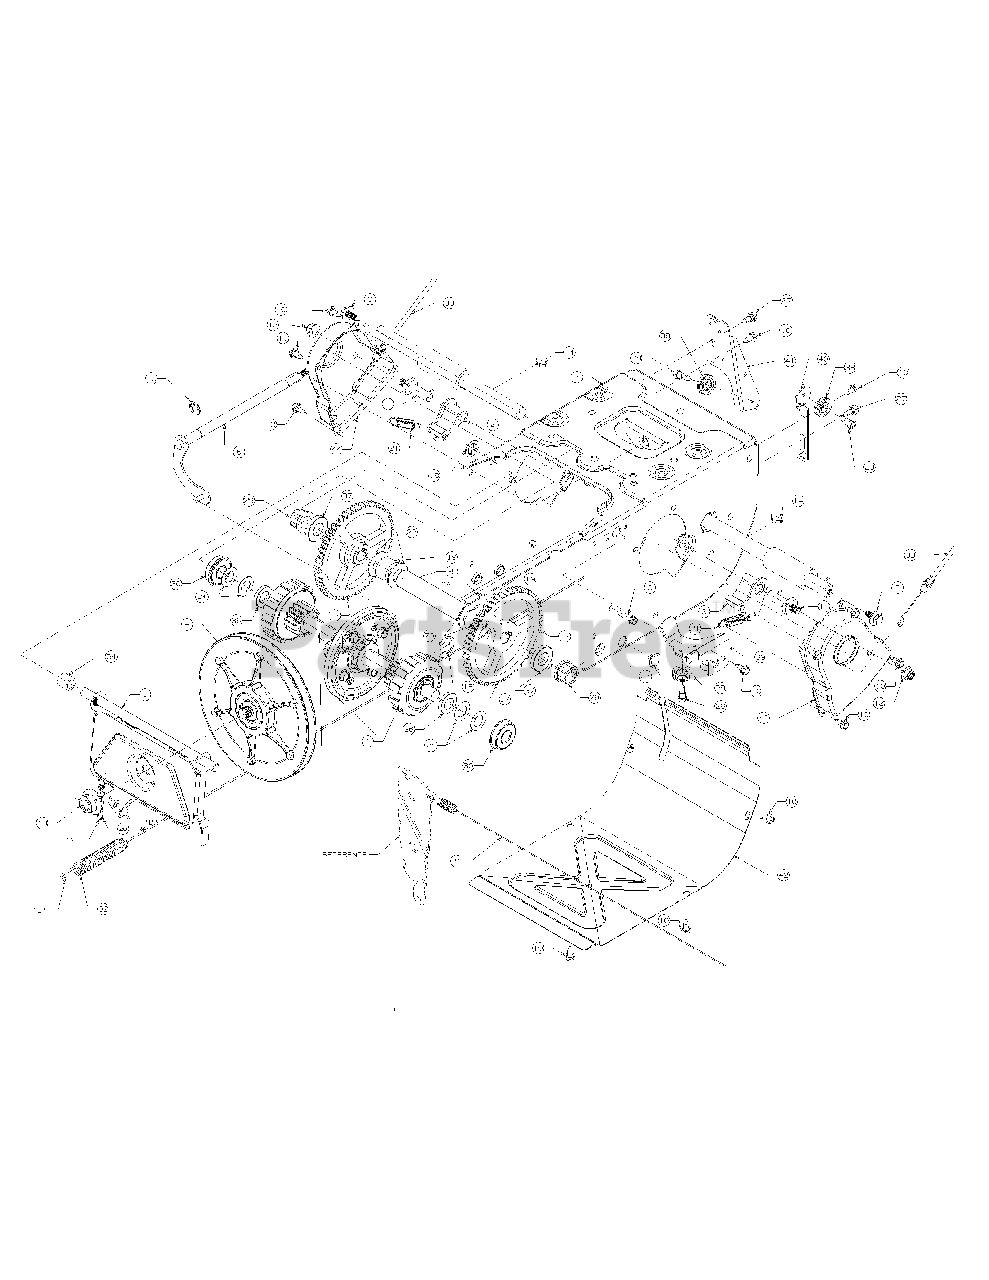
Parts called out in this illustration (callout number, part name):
1	Shift Asm-Plntr
2	Dogg Asm-RH
3	Dogg Asm-LH
4	Disc Assy-Friction
5	Bracket Assy-Support
6	Shift Asm-Rod S/T
7	Frame Asm-Drive
8	Hhcs-5/16-24 X .75
9	Screw-Tap 1/4-20
10	Screw Hex.Wash.Hd 1/4-20X.625
11	Shaft:Actr:Dr 500 S/
12	Nut-Flange Lk.Nylo
13	Nut-Hex Flange 5/8
14	Key 3/16 X 3/4 H
15	Ring-E For .500
16	Ring-Retaining-E T
17	Gear-56T
18	Cap-Push
19	Spacer: .76Id X .7
20	Spring-Extension
21	Spring:Extension
22	Plug-Hole 5/8
23	Washer-Fl-.760Id X
24	Washer-Flat .67X 1
25	Grease
26	Grease
27	Screw:Shoulder
28	Screw-1/4-28 X .32
29	Flange Bearing
30	Ball Bearing
31	Cable: Clutch
32	Cable-Drive Whe
33	Cable-Steering
34	Spacer-.513 Id X .
35	Tube:Supt:Axle
36	Spacer
37	Spacer-Axle
38	Roller-Cable Guide
39	Bracket-Auger Cable
40	Bracket:G
41	Bracket-Guide Clutch
42	Cover-Frame Snowth
43	Retainer-Strbl Drv Shf
44	Retainer-Strbl Drv Shf
